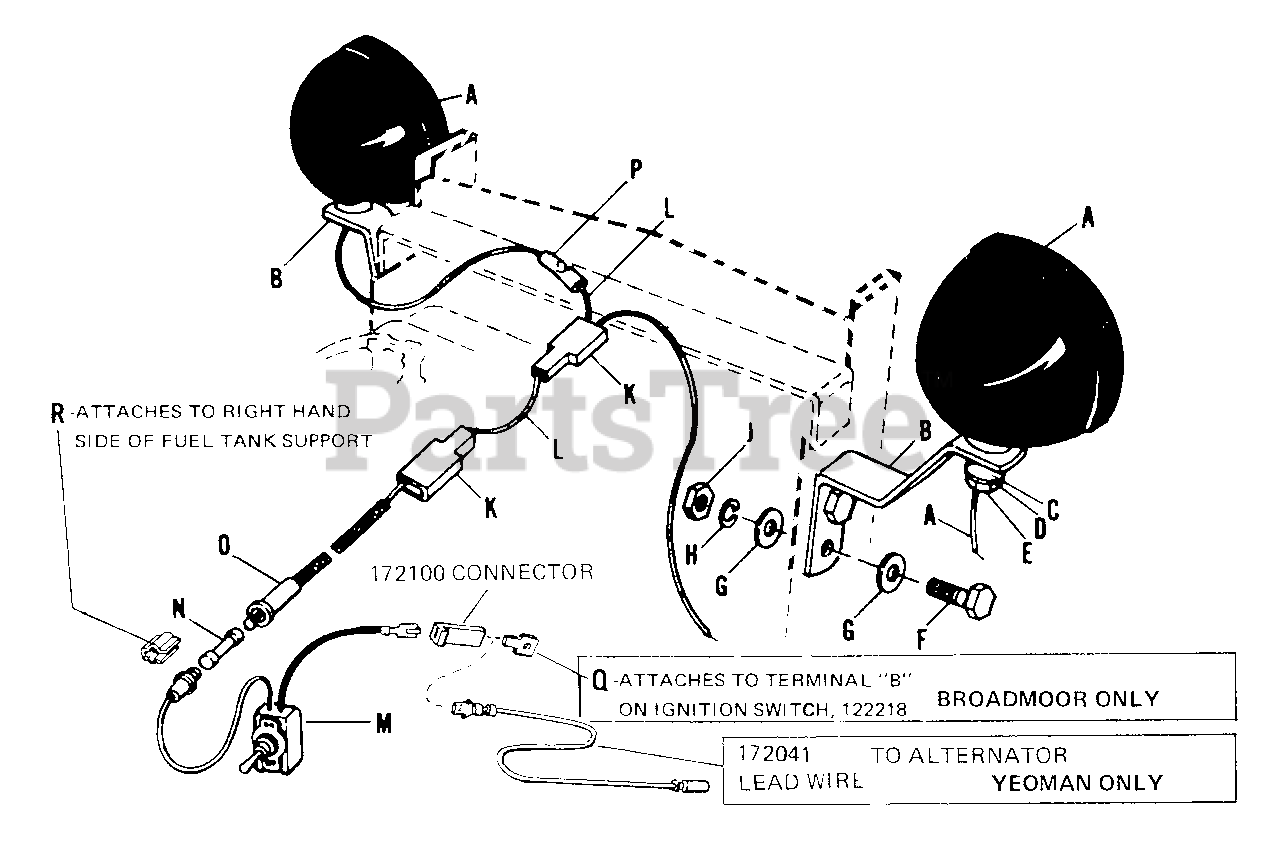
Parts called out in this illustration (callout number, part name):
A	Lamp Assembly
D	Lock Washer, 1/2"
E	Full Hex. Nut, 1/2"-13
F	Hex. Capscrew, 5/16"-18 x 1-1/2"
G	Plain Washer, 5/16"
H	Lock Washer, 5/16"
J	Full Hex. Nut, 5/16"-18
K	Insulated Connector
L	Extension Wire
M	Toggle Switch (with hardware)
N	Fuse 20 Amp.
O	Wire Connector
P	Connector
R	Fuse Clip
